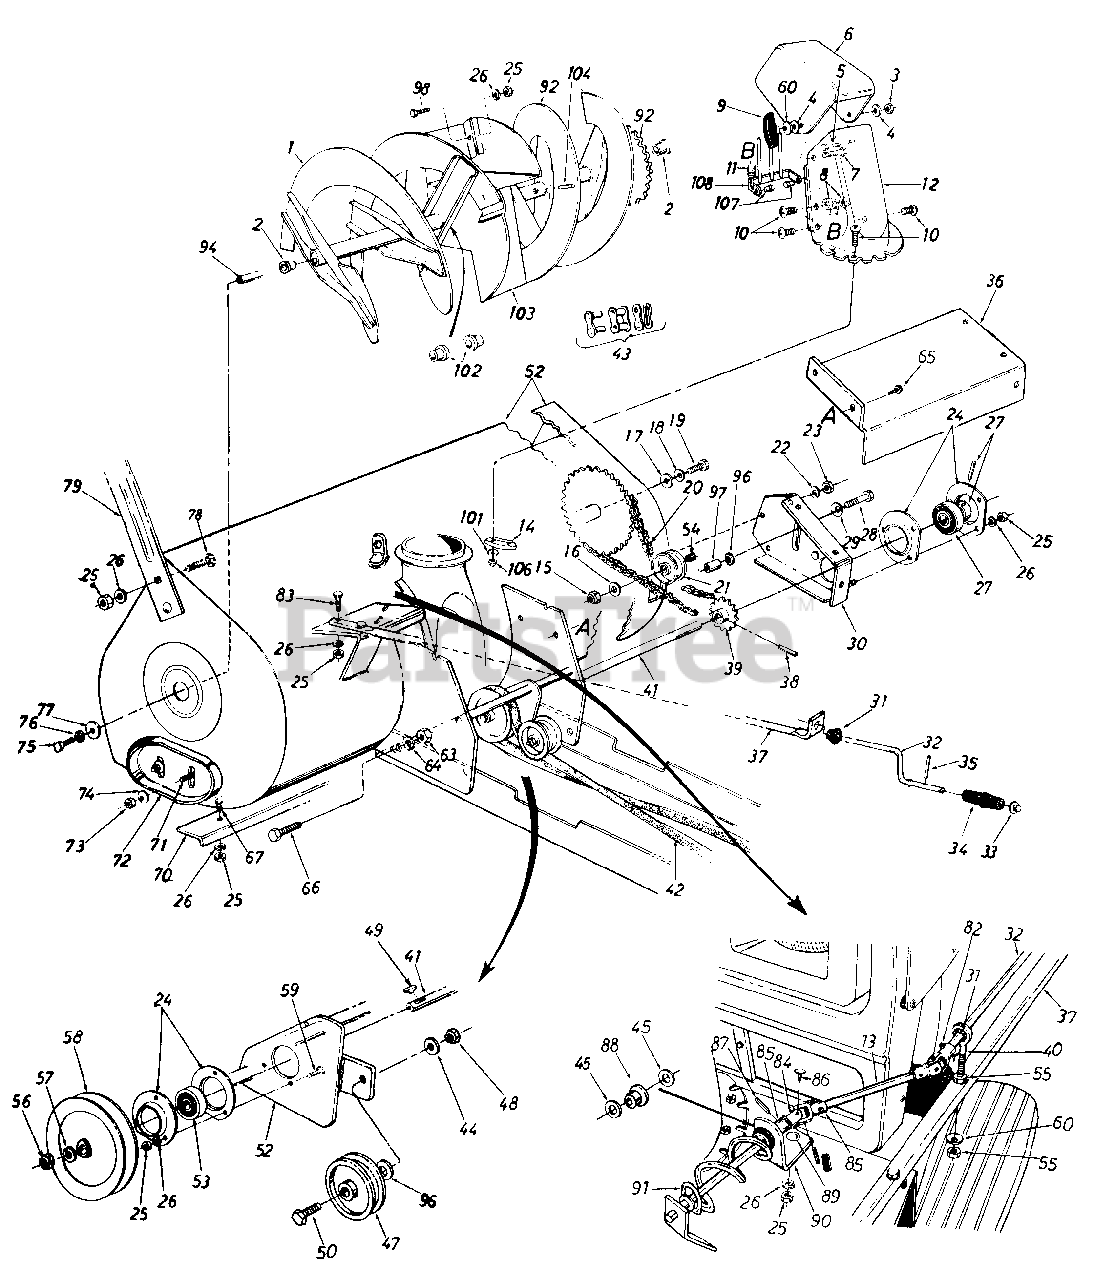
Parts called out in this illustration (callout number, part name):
3	Hex Cent. L.-Nut 5/16-18 Thd.
4	Fl.-Wash. .344" I.D.
5	Truss Mach. Scr. 5/16-18 x .75" Lg.
6	Upper Chute
7	Carriage Bolt 5/16-18x 1.0" Lg.
8	Hex L-Nut 1/4-20 Thd.
9	Hand Knob
10	Truss Mach. Scr. 1/4-20 x .75" Lg.
11	Ext. Spring
12	Lower Chute
13	Chute Crank Extension Rod
14	Chute Flange Keeper
15	L.-Nut 3/8-16 Thd.
16	Fl.-Wash.
17	Fl.-Wash.
18	Belleville Wash.
19	Hex Bolt 1/2-13 x 1.00" Lg.
20	#420 Chain 1/2" Pitch x 77 Links
21	Plastic Idler 2.00" O.D.
22	L.-Wash. 1/4" I.D.
23	Hex Nut 1/4-20 Thd.
24	Bearing Housing
25	Hex Nut 5/16-18 Thd.
26	L.-Wash. 5/16" I.D.
27	Self-Aligning Bearing
28	Hex'Bolt 3/8-16 x 1.75" Lg.
29	Belleville Wash. 3/8" I.D.
32	Chute Crank .375 Dia. x 34.5" Lg.
33	Push Nut 3/8" Rod
34	Knob
35	Roll Pin
39	14 Teeth Sprocket Ass'y.
40	Eyebolt 5/16-18 x 3.0" Lg.
41	Drive Shaft
42	"V" Belt
43	Master Link for #420 Chain
44	L.-Wash. 3/8" I.D.
45	Fl.-Wash. .385 I.D. x .62" O.D.
47	Fl.-Idler with Flanges
48	Hex Jam L.-Nut 3/8-16 Thd.
49	#61 Hi-Pro Key 3/16 x 5/8" Dia.
50	Hex Bolt 3/8-16 x 1.75" Lg.
52	Spiral Housing Ass'y.
53	Self-Aligning Bearing
54	Sleeve Bearing .50" I.D.
55	Hex Nut 5/16-18 Thd.
56	Hex Nut 3/4-10 Thd.
57	L.-Wash. 3/4" I.D.
58	"V"Pulley .750" I.D. x 6.00" O.D.
59	Hex Sems Bolt 5/16-18 x .75" Lg.
60	Bell-Wash. .345" I.D. x .88" O.D.
63	Hex Nut 1/2-13 Thd.
64	L.-Wash. 1/2" I.D.
65	Hex Wash. Hd. Tap Scr. 1/4-20 x .50" Lg.
66	Hex Bolt 1/2-13 x 2.75" Lg.
67	Carriage Bolt 5/16-18 x .75"
72	Skid Shoe
73	Hex Jam Nut 3/8-16 Thd.
74	Belleville Wash. 3/8" I.D.
75	Hex Bolt 1/2-13 x 1.00" Lg.
76	Belleville Wash. 1/2" I.D.
77	Fl.-Wash.
78	Carriage Bolt 5/16-18 x .62" Lg.
82	Cotter Pin
83	Hex Bolt 5/16-18 x 1.50" Lg.
84	Joint Block
85	Joint Bracket Ass'y.
86	Oval Head Rivet
87	Spring Pin Roll 1/8" Dia. x .75" Lg.
88	Nylon Bushing
89	Carriage Bolt 5/16-18 x .75" Lg.
90	Chute Crank Bracket
91	Chute Crank Ass'y.
96	Flat Washer
97	Idler Spacer
98	Carriage Bolt 5/16-18 x .75" Lg.
101	Fl.-Wash. 1/4" I.D.
102	Plastic Bushing
106	Hex L.-Nut 1/4-20 Thd.
107	Shld. Nut 1/4-20 Thd.
05139A-0637	BLADE-GUIDE (DRIFT - POWDER BLACK (0637)
05139A-0638	BLADE-GUIDE (DRIFT - MTD/TROY-BILT RED (0638)
05139A-0662	BLADE-GUIDE (DRIFT - OYSTER GRAY (0662)
05139A-0665	BLADE-GUIDE (DRIFT - YARDMAN GREEN (0665)
05139A-0674	BLADE-GUIDE (DRIFT - YARDMAN YELLOW (0674)
05139A-0716	BLADE-GUIDE (DRIFT - CUB YELLOW-99 (0716)
